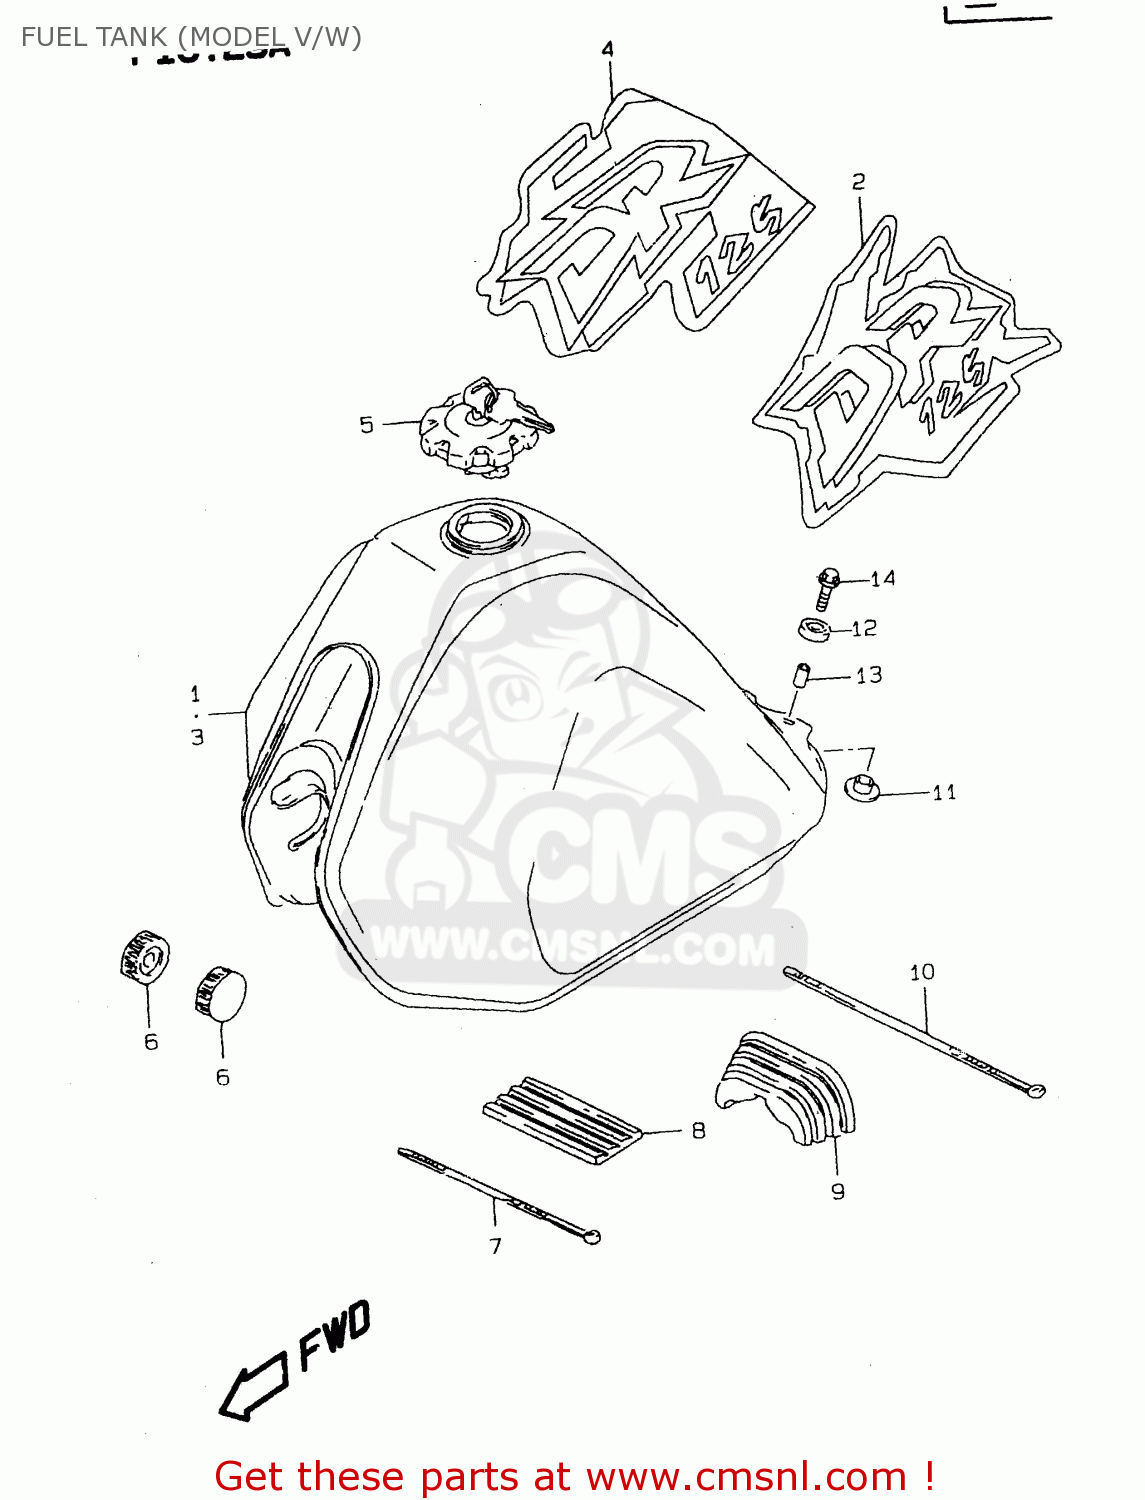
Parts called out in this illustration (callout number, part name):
1	TANK DR125SE/V
2	TAPE SET, FUEL TANK
3	TANK ASSY,FUEL(BLACK)
4	TAPE SET,FUEL TANK
5	CAP SET,FUEL TANK
6	CUSHION
7	CLAMP(L:250)
8	CUSHION,FUEL TANK UPR FR
9	CUSHION,FUEL TANK RR
10	CLAMP(L:300)
11	CUSHION
12	CUSHION
13	SPACER(6.5X9X18)
14	BOLT
